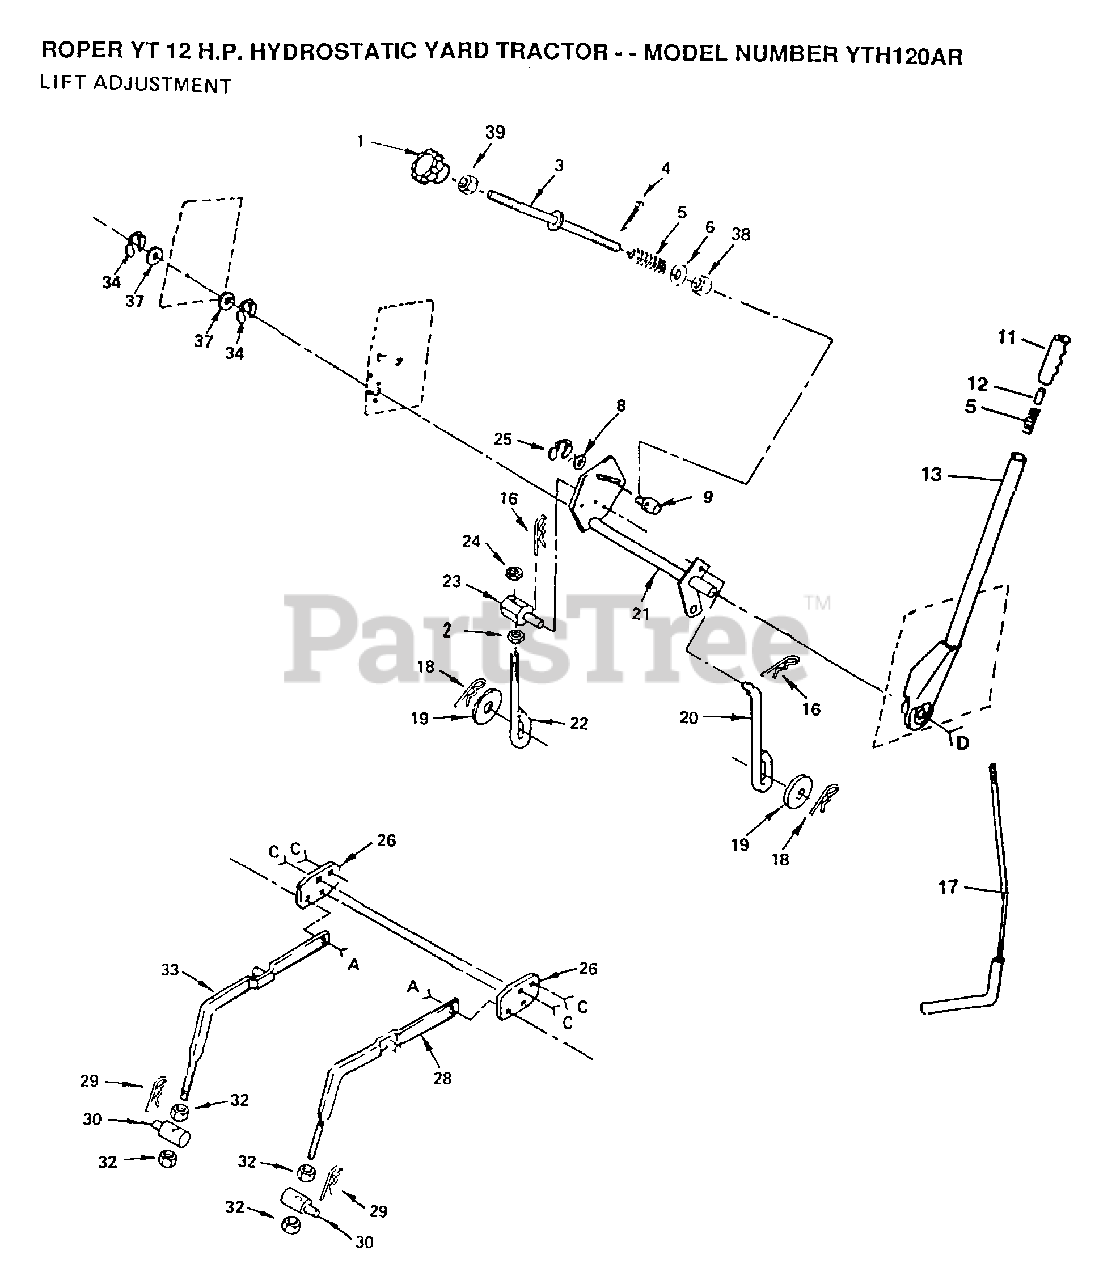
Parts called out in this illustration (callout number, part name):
1	HDLE ADJ LIFT
2	NUT
3	ROD LIFT LT
5	SPRING T
6	WASHER
8	WASHER
9	TRUNION LT
11	GRIP
17	LEVER ROD LT
18	SPRING.RETAINER
20	LIFT LINK LT
21	SHAFT LIFT LT
22	PIVOT PIN T
25	KLIP RING
26	"BRACKET, SUSPE T"
28	RH SUSP ARM ASM
29	SPRING H
32	NUT
33	LH SUSP ARM ASM
34	E-RING
37	WASHER
38	NUT T
39	NUT
